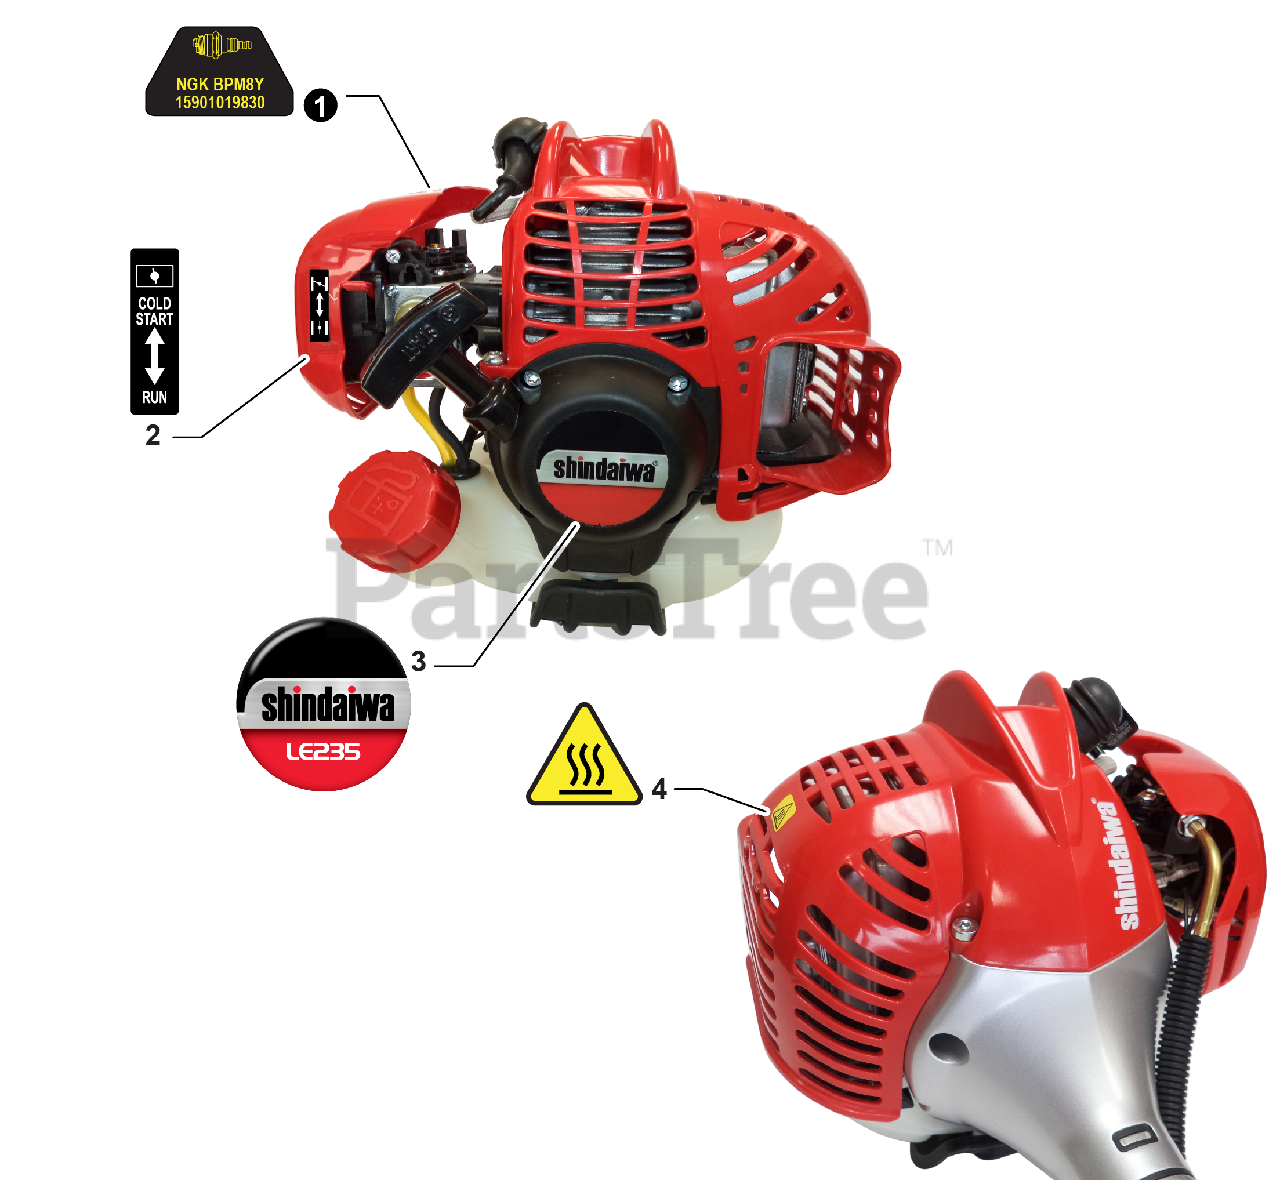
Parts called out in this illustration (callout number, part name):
1	LABEL - SPARK PLUG - BPM8Y
2	LABEL - CHOKE
3	LABEL - SHINDAIWA - LE235
4	LABEL - CAUTION - HOT
